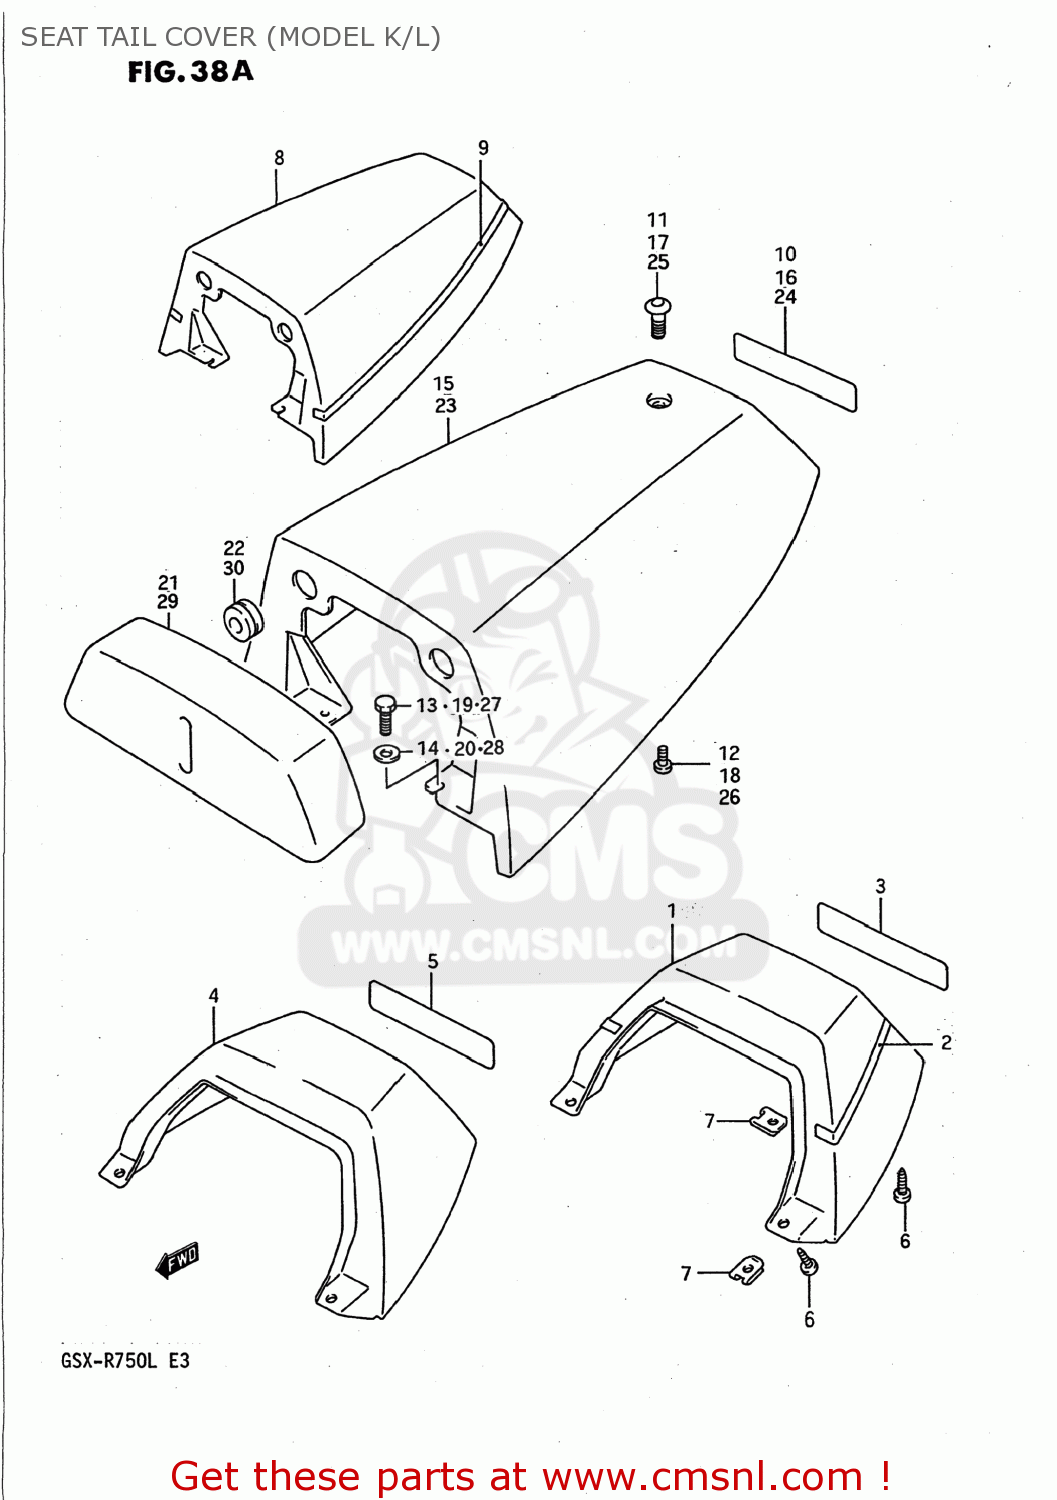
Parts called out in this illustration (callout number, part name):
1	COVER,SEAT TAIL
2	TAPE,SEAT TAIL COVER
3	EMBLEM
4	COVER COMP,SEAT TAIL
5	EMBLEM
6	SCREW
7	NUT
8	BOX ASSEMBLY,SEAT TAIL
9	TAPE,BOX SEAT TAIL COVER
10	EMBLEM
11	SCREW(6X16)
12	SCREW
13	BOLT,M6X1X20
14	WASHER,LOCK
15	BOX ASSEMBLY,SEAT TAIL
16	EMBLEM
17	SCREW(6X16)
18	SCREW
19	BOLT,M6X1X20
20	WASHER,LOCK
21	BACKREST,SEAT
22	CUSHION
23	BOX SET,SEAT TAIL
24	EMBLEM,BOX SEAT TAIL
25	SCREW(6X16)
26	SCREW
27	BOLT,M6X1X20
28	WASHER,LOCK
29	BACKREST,SEAT
30	CUSHION
